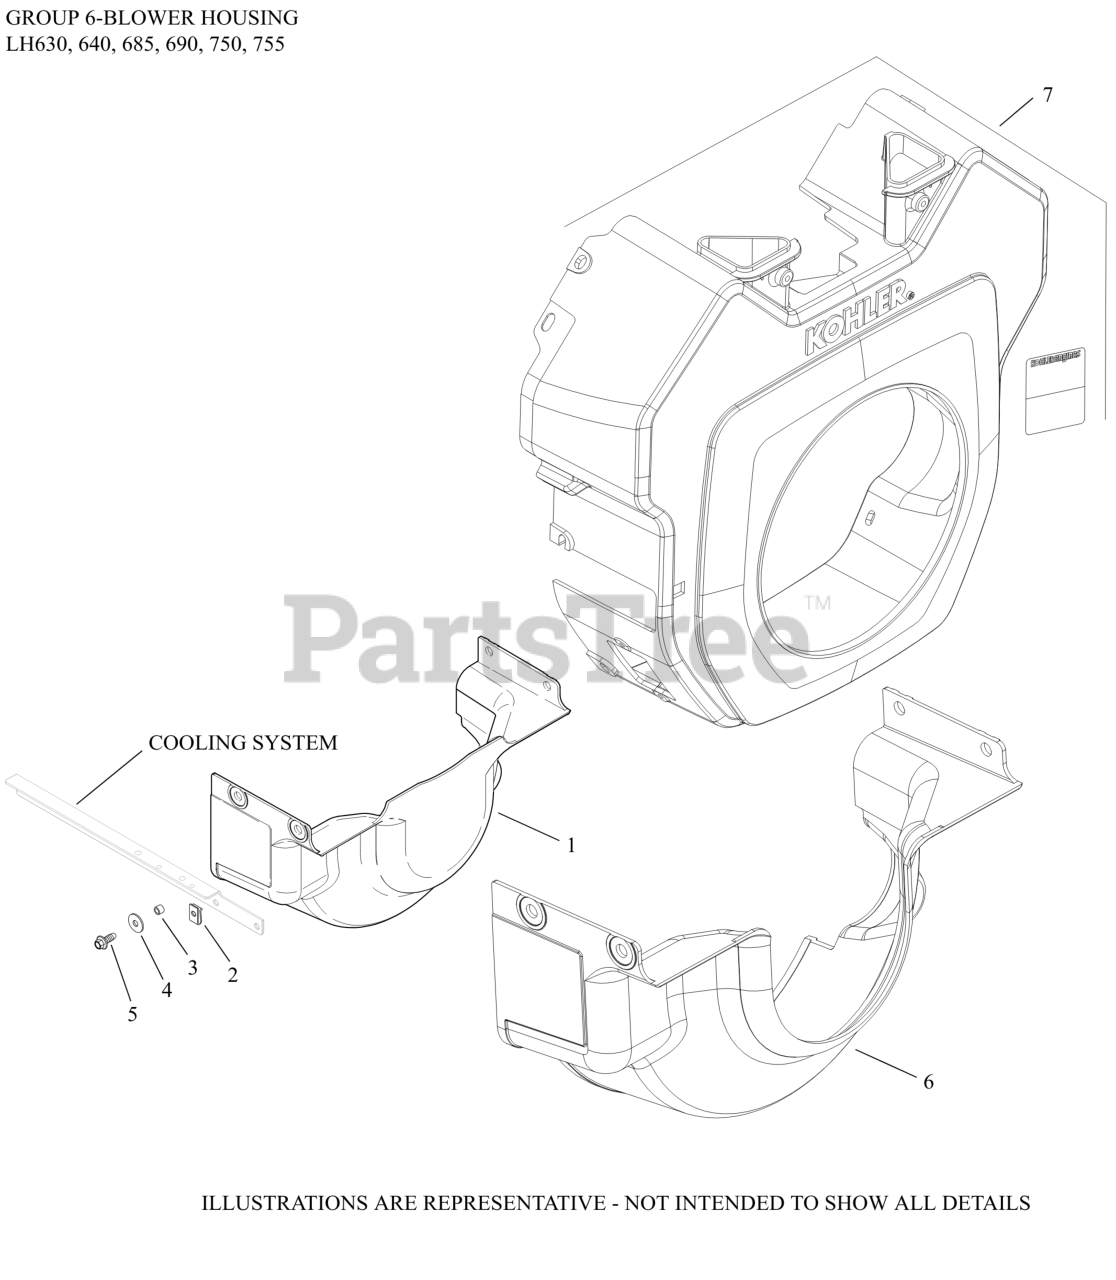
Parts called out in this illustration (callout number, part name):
1	COVER, ENGINE FLYWHEEL
4	WASHER, FLAT 1/4"
5	SCREW, THREAD FORMING
